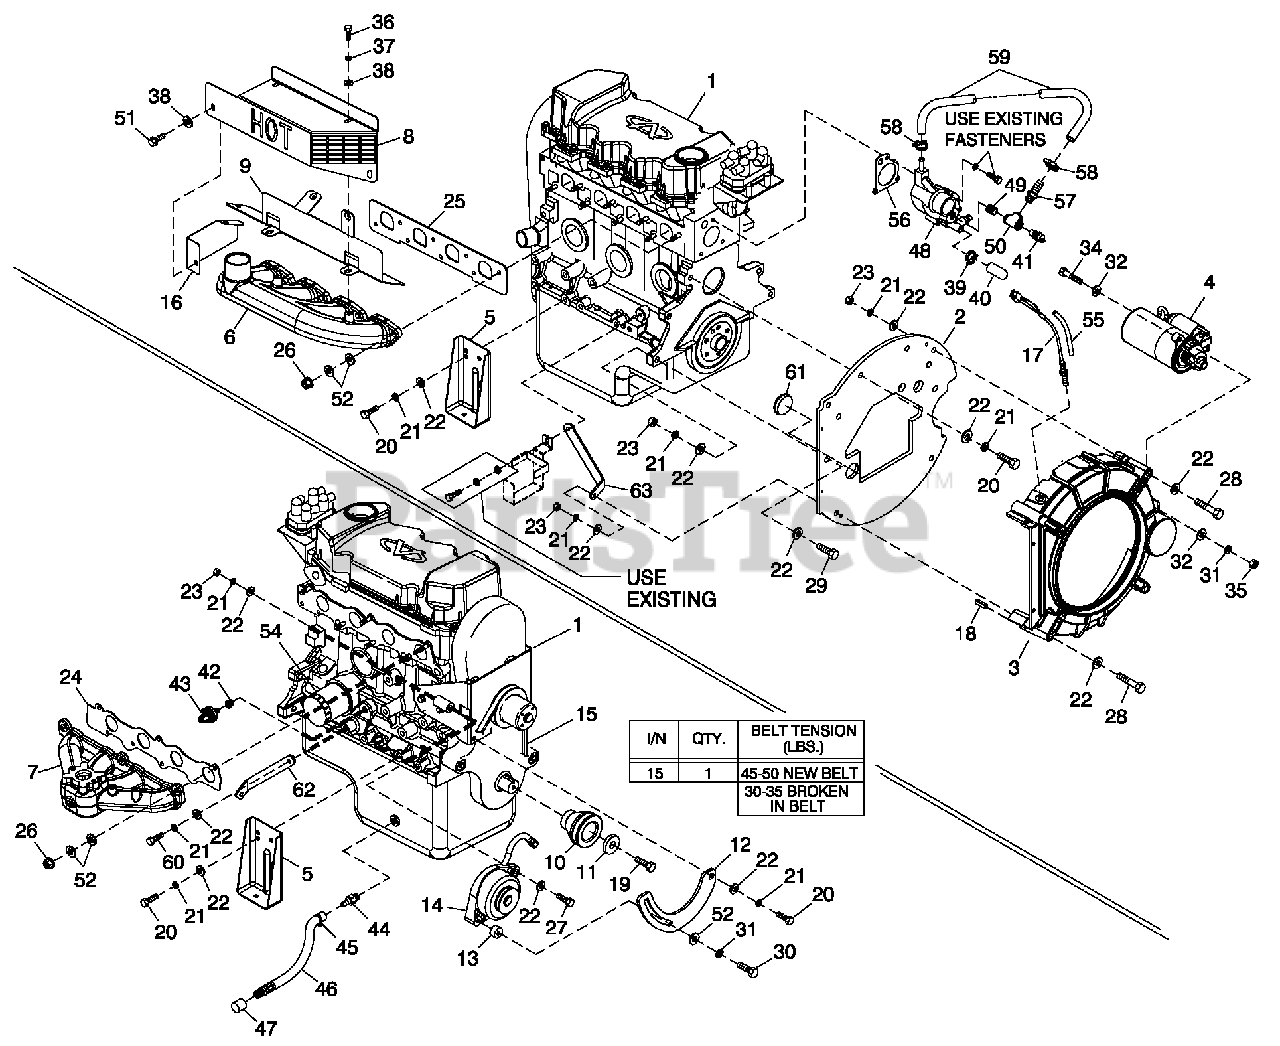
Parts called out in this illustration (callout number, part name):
1	ENGINE GENERAC 1.6L NG
2	ENGINE PLATE 1.6L
3	HOUSING BLOWER MACHINED 1.6L
4	STARTER 12 VOLT
5	ENGINE MOUNTING FOOT STAMPING
6	EXHAUST MANFOLD 1.6L MACHINED
7	INTAKE MANIFOLD MACHINED 1.6L
8	HEAT SHIELD LOWER 1.6L
9	HEAT SHIELD UPPER 1.6L
10	PULLEY CRANKSHAFT MACHINED
11	WASHER PULLY
12	BRACKET TENSIONER
13	SPACER ALTERNATOR
14	DC ALTERNATR HAN-KOK
15	V-BELT 3/8 X 30.6
16	HEAT SHELD FRONT 1.6L
17	ASSY MAGPICKUP (3/8-24 MALE)
18	PIN SPRING 1/4 X 3/4
19	SCREW HHC M12-1.5 X 40 G10.9
20	SCREW HHC M10-1.5 X 25 G10.9
21	WASHER LOCK M10
22	WASHER FLAT 3/8-M10ZINC
23	MIT JEX ,10-1/5 C;ASS 10ZINC)
24	GASKET INTAKE MANIFOLD 1.6L
25	GASKET EXHAUST MANIFOLD 1.6L
26	NUT TOP LOCK FL M8-1.25
27	SCREW HHC M10-1.5 X 85 G8.8
28	SCREW HHC M10-1.5 X 11 G10.9
29	SCREW HHC M10-1.5 X 40 G 10.9
30	SCREW HHC M8-1.25 X 35 G8.8
31	WASHER LOCK M8-5/16
32	WASHER FLAT 5/16-M8 ZINC
33	TIE WRAP UL 7.4" X 10" BLK
34	SCREW HHC M8-1.25 X 40 G8.8
35	NUT HEX M8-1.25 G8 CLEAR ZINC
36	SCREW HHC 1/4-20 X 1/2 G5
37	WASHER LOCK M6 1/4
38	WASHER FLAT 1/4-M6 ZINC
39	CLAMP HOSE #10 .56-1.06
40	CAP ANTIFREEZE RUBBER
41	SWITCH HI-TEMP 245 D X 3/8 NPT
42	BSHG RDCR HEX 1/4 TO 1/8
43	SWITCH OIL PRESSURE 10PSI 2POL
44	DECAL DANGER HIGH VOLTAGE BI
45	CLAMP HOSE- OIL DRAIN
46	HOSE OIL DRAIN ASSY 21"
47	CAP HEX 1/4 NPT BRASS
48	THERMOSTAT HOUSNG MACHIND 1.6L
49	NIPPLE PIPE 3/8 NPT X 1-1/2
50	PIPE TEE 3/8 NPT
51	SCREW HWHTF M6-1.0 X 16
52	WASHER FLAT .34ID X .75 OD
54	OIL FILER 1.6L
55	REFLEX WRAP 13MM 13 X 460 (6"LG)
56	GASKET T-STAT HOUSING 1.6L
57	BARBED STR 3/8 NPT X 3/8
58	CLAMP HOSE .38-.87
59	HOSE 3/8 ID LOW PRES OIL/WATER (11"LG)
60	SCREW HHC M10-1.5 X 20 G8.8
61	CAP, 1.5" HOLE SHALLOW
62	STRUT RH 1.6 L ENG ADAPT PLAT
63	STRUT RH 1.6 L ENG ADAPT PLAT
